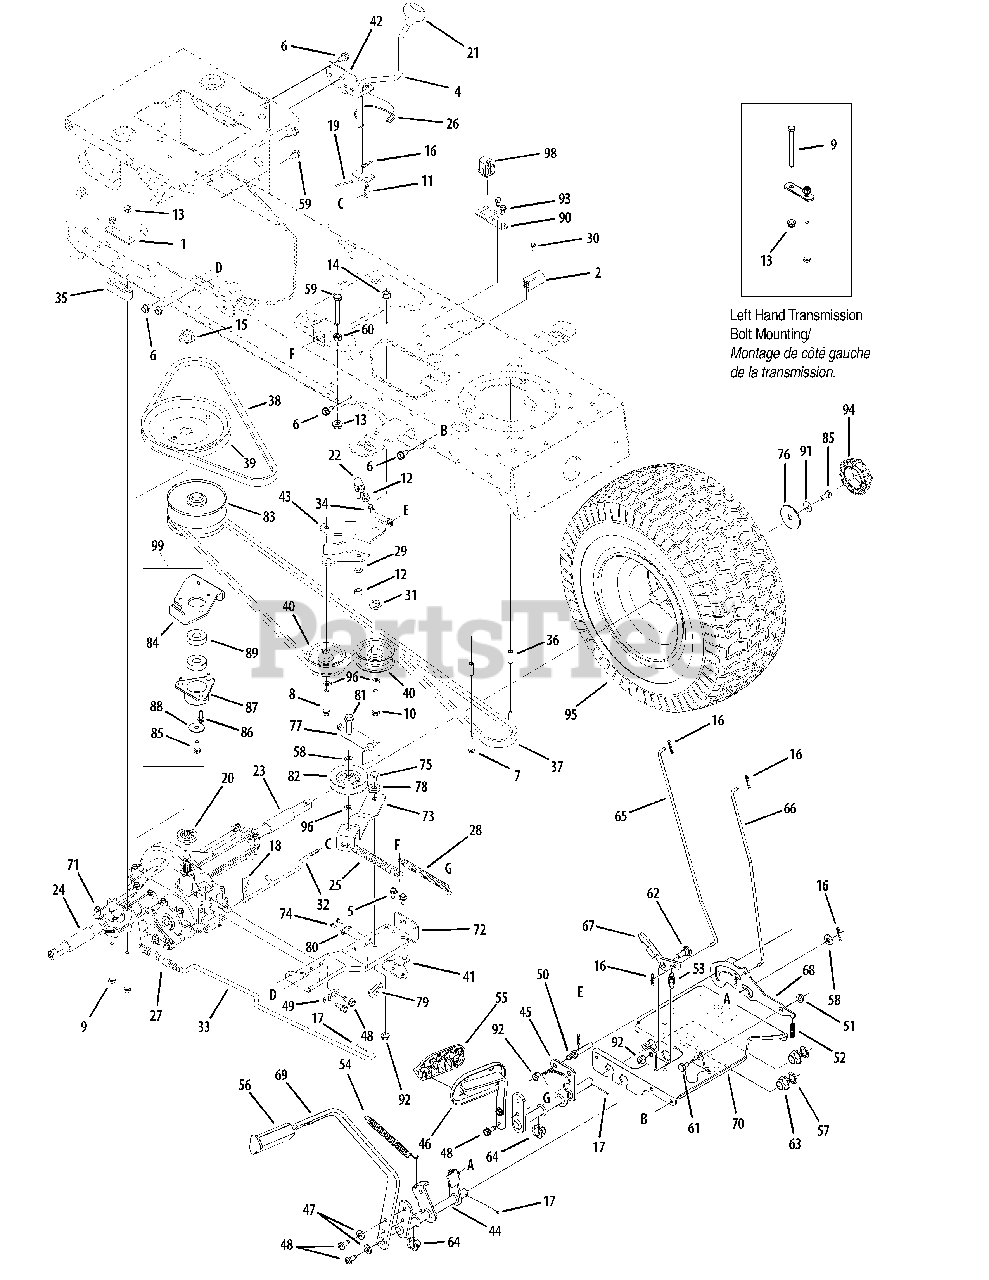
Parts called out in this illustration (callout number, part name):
1	Transaxle Mtg. Brkt.
2	Inter lock Switch
4	Shift Lever Ass’y
5	Hex Wash HD S-Tapp Scr 5/16-18 x .50
6	S-Tapp Scr 5/16-18 x .75
7	Hex Bolt 1/4-20 x 1.25
8	Hex L-Wash HD Scr 3/8-16 x 1.5
9	Hex Bolt 5/16-18 x 3.5" Lg.
10	Hex Bolt 3/8-16 x 2.0" Lg. (Gr. 5)
11	Adjustment ferrule
12	Hex Nut 3/8-24
13	Flange Locknut 5/16-18 Gr. F, Nylon
14	Flange Locknut 3/8-16 Gr. F
16	Int. Cotter Pin .072 x 1.13" Lg.
17	Cotter Pin 3/32 dia x 1.00 Lg.
19	Cotter Pin 1/8" Dia x 1.25
20	Pulley Hub 5/8" Spline
22	Drag Link Ball Joint
23	Sleeve, .758 x .821 x 3.3125
24	Sleeve, .758 x .821 x 2.4375
25	Extension Spring .62 dia. x 6.12
26	Complete Spring Clip
27	Extension Spring .59 x 4.0
28	Extension Spring, .50 Dia. x 6.37
29	L-Wash 3/8 ID
30	Shld. Scr. #10-32 x .5
31	Shoulder Spacer
34	Idler Adjustment Rod, 3/8
35	Transaxle Spacer
36	Spacer .260 x .375 x 1.030 Lg.
37	Variable-speed Belt
39	Pulley, V-Type, 7.25 dia.
40	Idler Pulley, Flat 2.75 OD
41	Shift Bracket
42	Shift Bracket F-N-R
44	Brake Control Assembly
46	AutoDrive Pedal Assembly
47	L-Wash 5/16 ID
48	Hex Wash. Hd. Scr. 5/16-18 x .75 Lg.
49	Flat Washer .344 ID x .625 OD x .063
50	Pin 3/8-16 x 2.68 Lg.
51	Hex Flange L-Nut 5/16-18
52	Compression Spring
53	Extension Spring, .50 OD x 1.41
54	Extension Spring, .50 Dia. x 6.37
55	AutoDrive Pedal Pad
57	Flat Washer .640 ID x 1.24 OD x .06
58	Flat Washer .38 ID x .87 OD x .09
59	Hex Hd Cap Scr. 5/16-18 x 2.0 Gr. 5
60	Hex Nut 516-18 Gr. 5
61	Shld. Scr .437 Dia x .162 Lg.
62	Shoulder Screw .500 x .25
63	Hex Flange Bearing .630 ID
64	Hex Flanged Bearing .628 ID
65	Brake Lock Rod
66	Cruise Control Rod
67	Cruise Control Latch
68	Lock out Bracket
70	Steering Support Bracket
71	Transmission Ass’y
72	Torque Bracket Assembly
73	Idler Bracket
74	Hex Wash HD AB S-Tapp Scr #8-.50
75	Hex Screw 3/8-16 x 1.25
76	Flat Washer .350 ID x 1.59 OD x .062
78	Shoulder Spacer .884 ID x .190
79	Short Spring Switch
80	Insulator Nut Plate
81	Sems Screw 3/8-16 x 2.5
82	Idler Pulley, V-Type 5L x 3.06
83	Variable Speed Pulley Ass’y 4.75 OD
84	Pulley Bracket
85	Hex L-Bolt 5/16-24 x .75 Gr. 5
86	Hex Wash HD Bolt 1/4-20 x 1.50" Lg.
88	Flat Washer .22 ID x 1.25
89	Ball Bearing
90	Switch Bracket, Parking Brake
91	Cupped Washer .345 ID x .88 OD x .060
92	Flange Lock-Nut 3/8-16 Gr. F Nylon
93	Hex Wash S-Tapp Scr 1/4-20 x .50
94	Hub Cap
95	Wheel Assembly Complete, 20 x 8 x 8
96	Flat Washer .406 ID x .812 OD x .134
99	Variable Speed Pulley Ass'y (Incl. Ref. Nos. 84-89)
